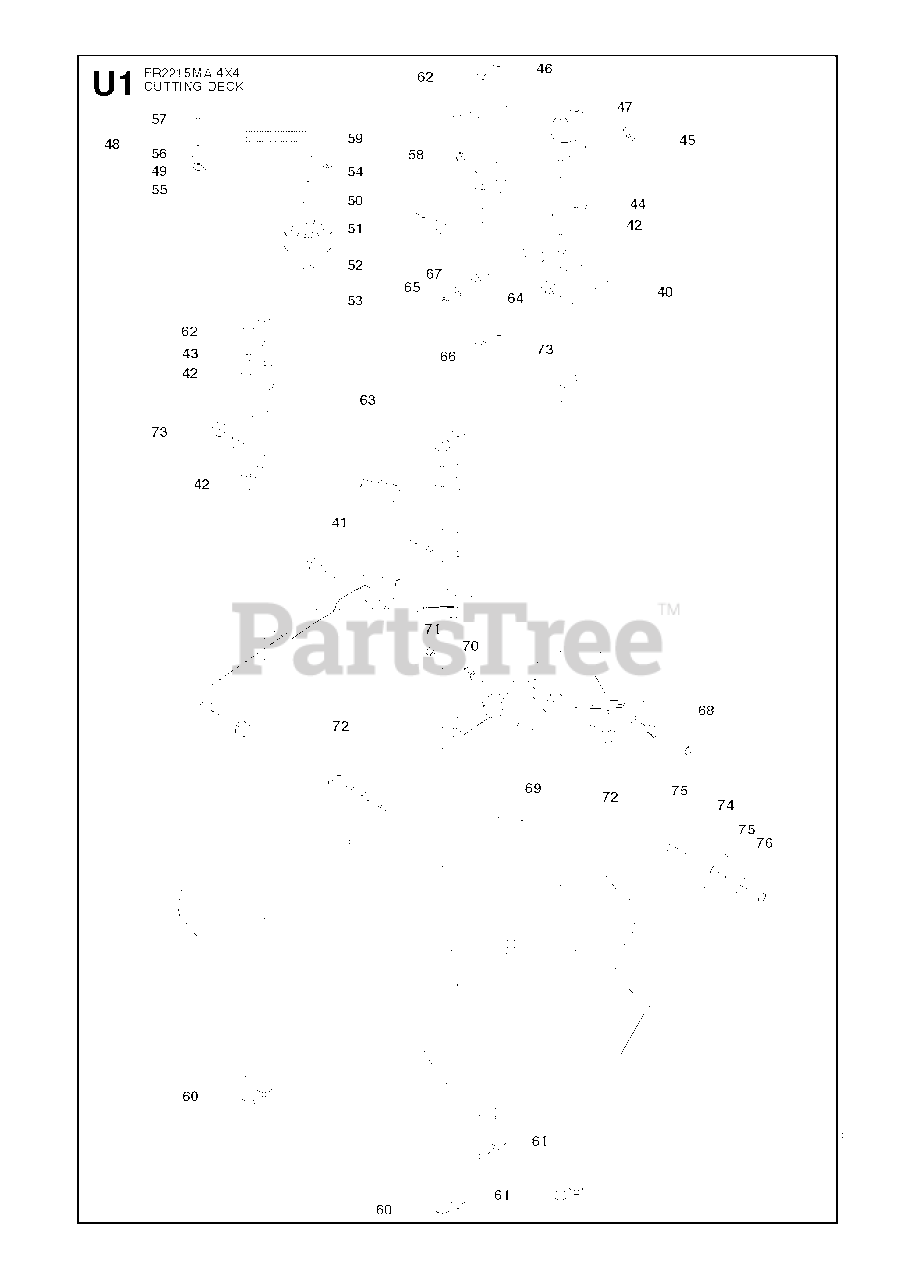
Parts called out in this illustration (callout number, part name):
51	PULLEY
52	SPACER
53	SCREW
54	LOCKNUT M8
55	BUSHING
56	SPACER
57	SCREW
58	LOCKNUT M8
59	SPRING
62	LOCKNUT M8
73	LOCKNUT M8
74	DECK ROLLER, FRONT
76	RETAINING RING SGA 15
